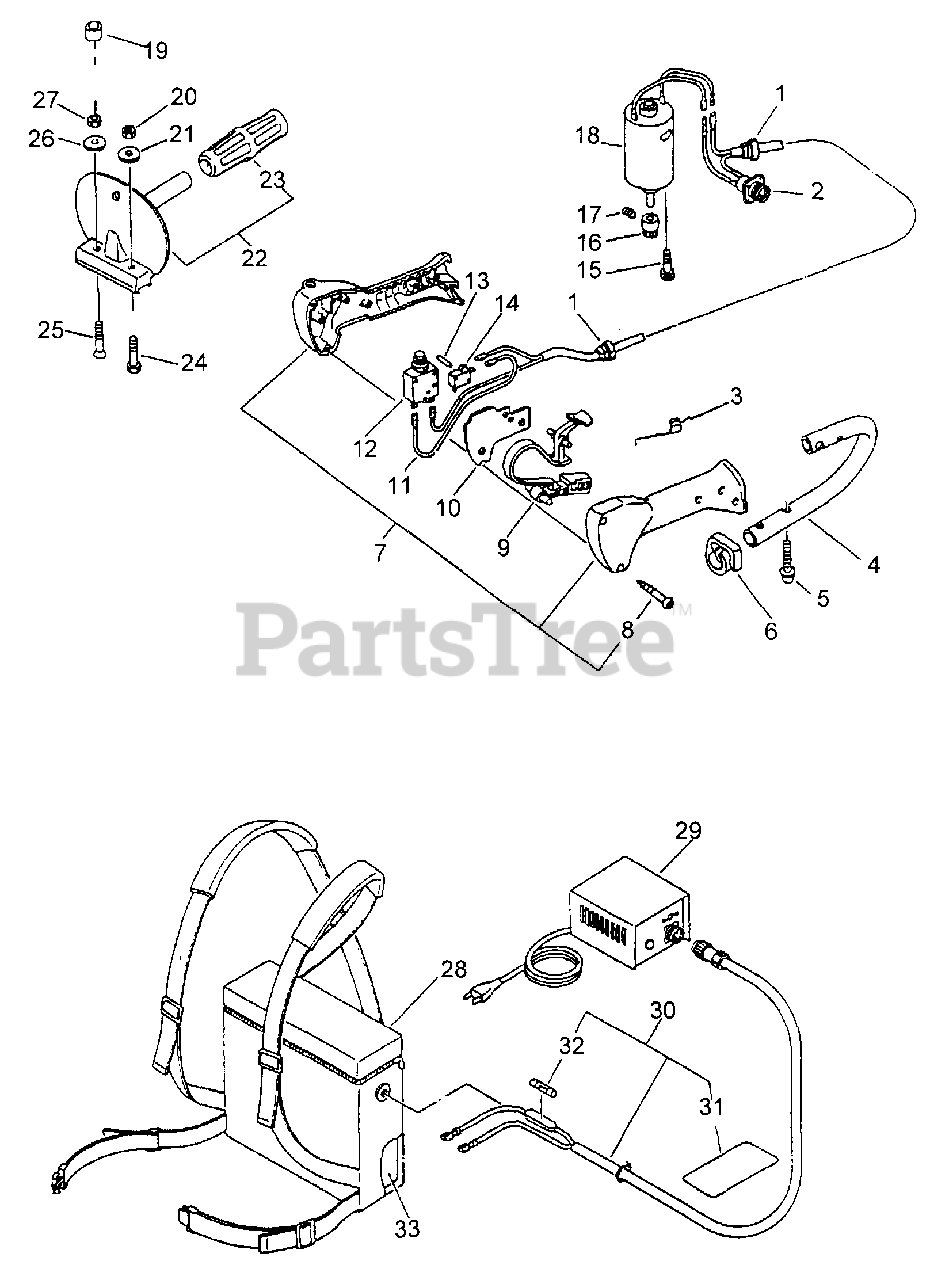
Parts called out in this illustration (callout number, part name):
1	GROMMET
2	HARNESS, WIRE
3	SPRING
4	HANDLE - REAR
5	SCREW - 5X25
7	HANDLE GRIP SET
8	SCREW - 4X22
9	TRIGGER, THROTTLE
10	PLATE, PARTITION
11	LEAD - GROUND
12	PROTECTOR, CIRCUIT
13	PIN
14	IGNITION SWITCH ASSY
15	SCREW - 5X30
16	GEAR - SPUR
17	SCREW - 4X5 -- SET
18	MOTOR ASSY
19	INSERT
22	HANDLE ASSY
23	GRIP, HANDLE - FRONT
24	BOLT - 6X35
25	SCREW - 5X30
26	WASHER - 5
27	LOCKNUT - 5
28	CASE, BATTERY
30	HARNESS, WIRE
31	LABEL - CAUTION
32	FUSE
